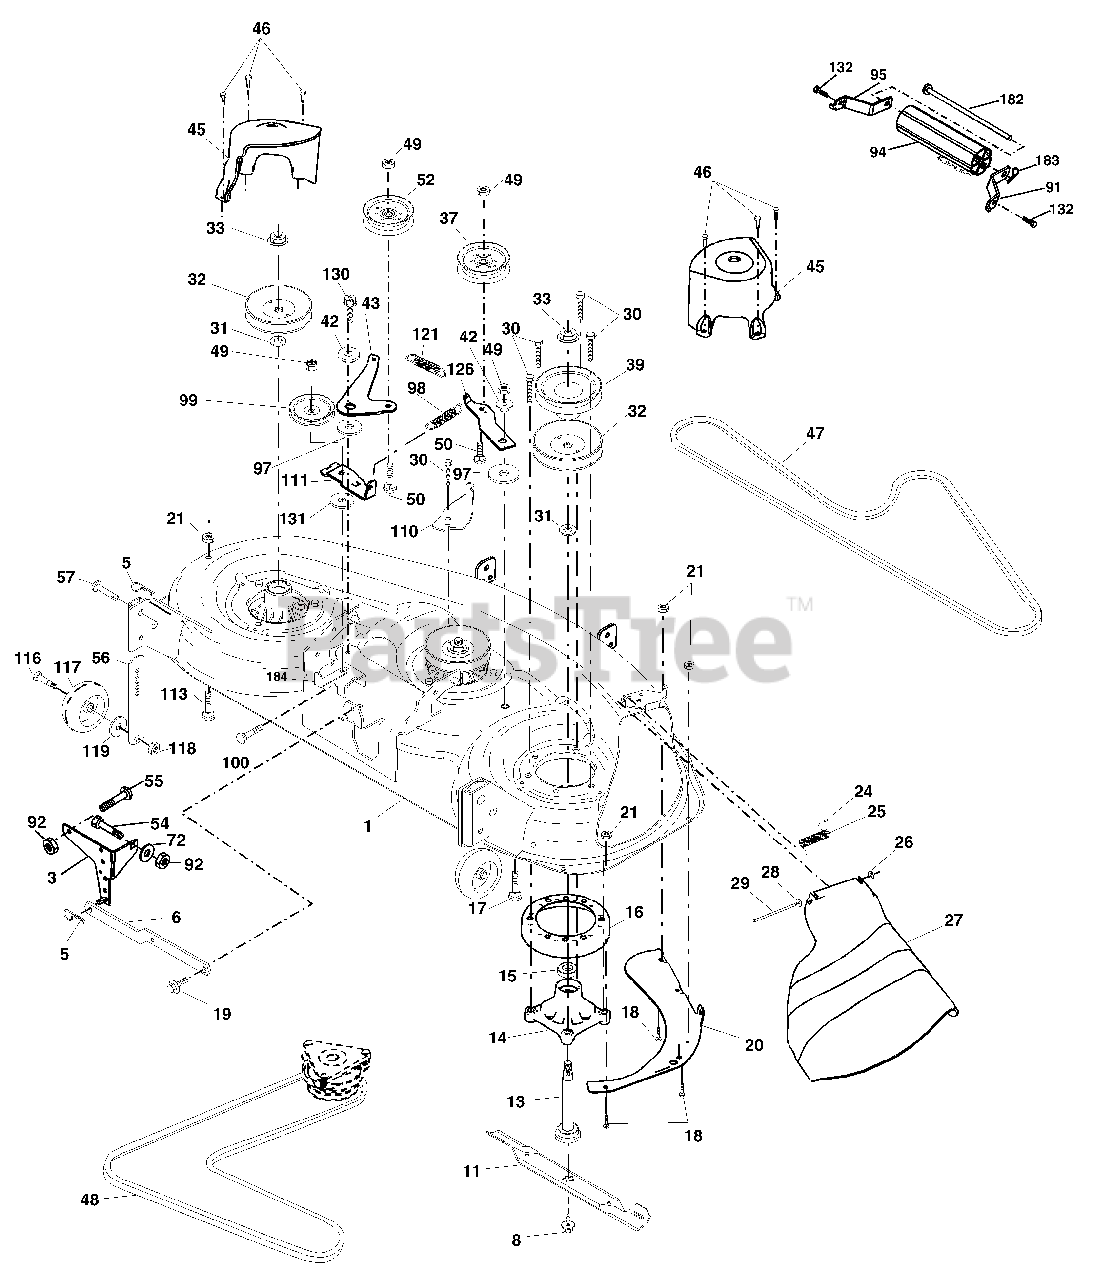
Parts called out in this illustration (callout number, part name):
1	Deck Weldment Mower 48
3	Bracket Asm., Sway Bar
5	Retainer Spring
6	Bar Sway Deck
8	Bolt, 7/16 Asm. Blade
13	Shaft Asm. Mandrel Sealed
14	Housing Mandrel 48"
15	Bearing, Ball, Mandrel
16	Stripper, Mower
17	Bolt Rdhd Sq Neck 3/8-16 x 1.25
18	Bolt, Carriage 5/16-18 x 5/8
19	Bolt, Hex Head, Shoulder 5/16-18
20	Baffle, Vortex Mower
21	Nut, Crownlock 5/16-18 unc
24	Cap, Sleeve
25	Spring, Torsion
27	Shield, Deflector Mower
28	Washer 11/32 x 5/8 x 16 Ga.
29	Rod, Hinge
30	Screw, Thdroll, Washer Head
31	Washer, Spacer Mower Vented
32	Pulley, Mandrel
33	Nut, Flg. Top Lock Cntr. 9/16
37	Pulley, Idler, Flat
39	Pulley, Idler, Driven
42	Spacer, Retainer
43	Arm, Idler Secondary
45	Cover, Mandrel Deck
46	Screw, Thdroll. 1/4-20 x 5/8
47	V-Belt, Mower, Secondary
48	V-Belt, Mower, Primary
49	Nut, lock 3/8-16 unc
50	Bolt, Carriage 3/8-16 x 1-1/2 Gr. 5
52	Pulley Idler Flat 46 Pri. Drive
54	Bolt Fin Hex 3/8-16 x 1
55	Bolt Rdhd Sqnk 3/8-16 x 1
56	Bar Pnt Adjusting Wheel Gauge
57	Pin Head Rivet
72	Washer 13/32 x 13/16 x 12
91	Bracket, Asm Noseroller, RH 48
92	Nut Lock Hex w/Ins 3/8-16
94	Roller, Nose 48"
95	Bracket, Asm Noseroller LH 48
97	Washer Hardened
98	Spring Primary Drive
99	Pulley Idler "V"
100	Bolt RDHD Sqnk 3/8-16 unc x 2
110	Arm Spring Secondary
111	Arm Spring Fixed Tension
116	Bolt, Shoulder
117	Gauge Wheel
118	Nut, Centerlock 3/8-16 unc
119	Washer 3/8 x 7/8 x 14 Ga.
121	Spring Secondary Drive
126	Arm, Idler, Primary Deck
130	Screw 3/8-16 x 1.0
131	Washer 13/32 x 1 x 6 Ga.
132	Screw 3/8-16 x 3/4
133	Bolt Rdhd Sqnk 5/16-18 unc x 3/4
182	Rod Roller Nose
183	Retainer Spring
184	Keeper Belt Idler
